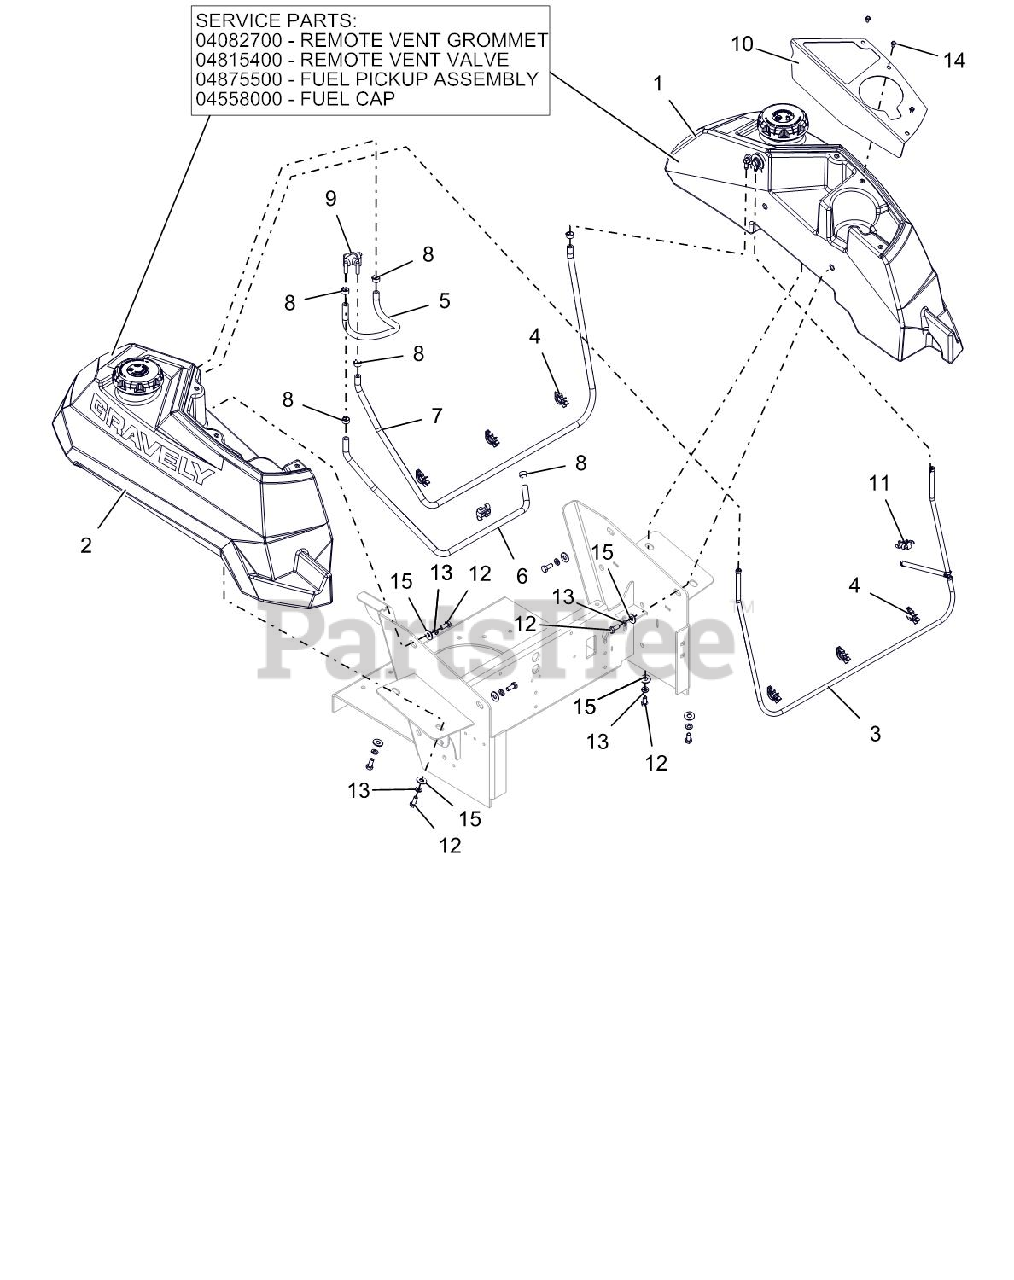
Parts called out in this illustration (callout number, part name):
1	ASM, LH - PT FUEL TANK
2	ASM, RH - PT FUEL TANK
3	ASM, VAPOR LINE
4	WIRE CLIP
5	HOSE, .25 LOW-PERM BULK GAS
6	HOSE, .25 LOW-PERM BULK GAS
7	HOSE, .25 LOW-PERM BULK GAS
8	CLAMP, FUEL LINE
9	VALVE, FUEL
10	PT CUPHOLDER PANEL - RED
11	CLIP, T, .38-.50
12	@BLT-HEX .31-18X.75 GR5 YWZC
13	@WSHR-LK .31X.078 REG YWZC
14	SCR-MCH 10-24X.38 HWHSTAINLESS
15	@WSHR-FL-STL.38X.875X.083 YWZC
16	GROMMET, REMOTE VENT NITRILE
17	VALVE, 2-WAY
18	ASSM,LRG TANK FUEL PICKUP LINE
19	CAP, FUEL VENTIN AUTOLOCK
